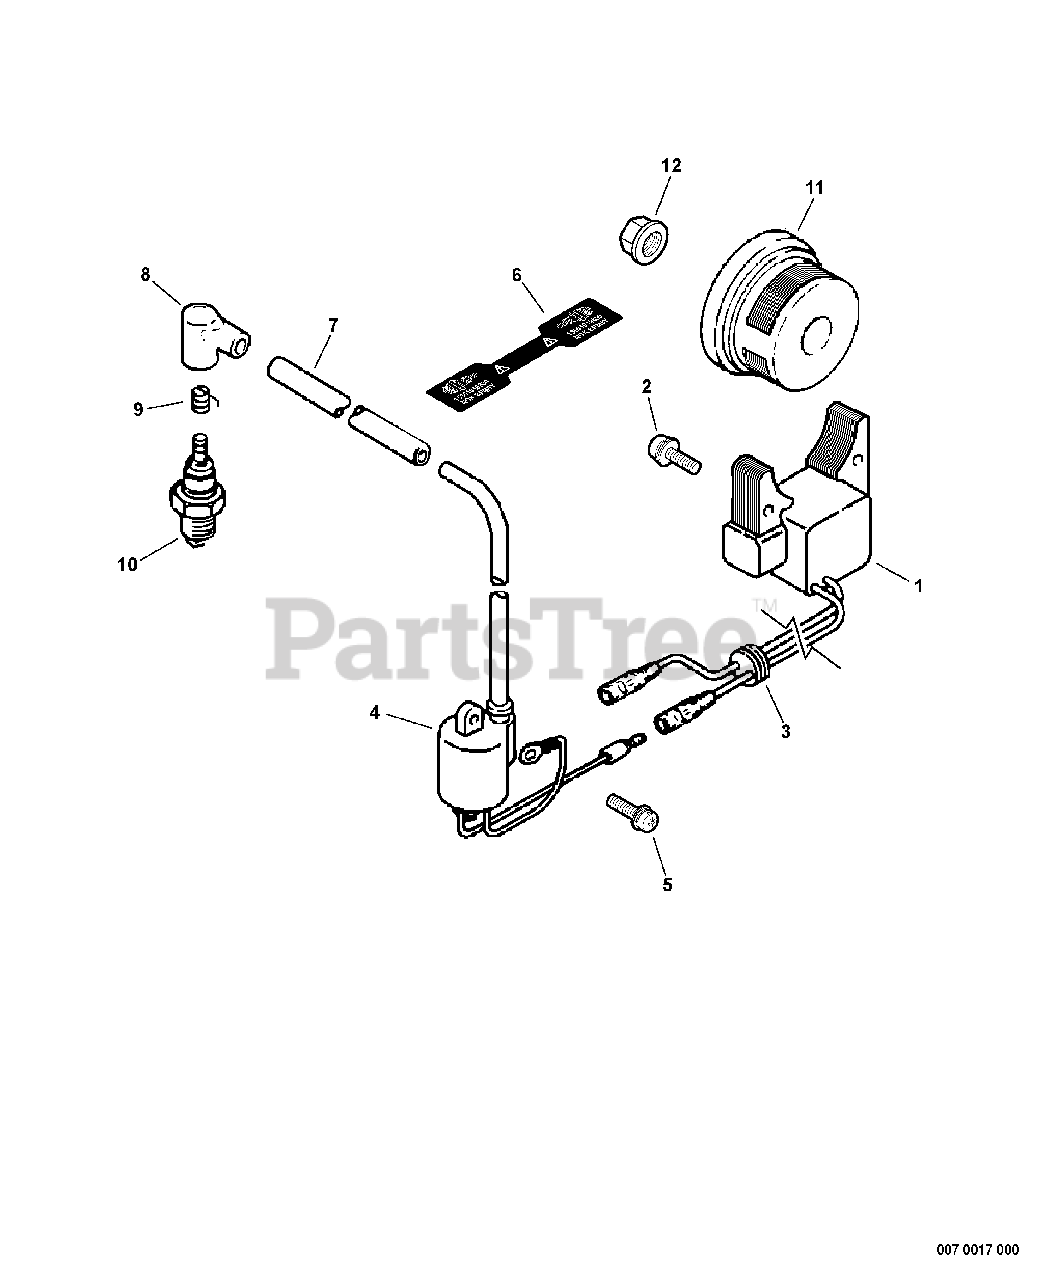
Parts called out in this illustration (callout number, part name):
1	COIL, IGNITION
2	SCREW - 5X25
4	COIL, IGNITION
5	SCREW - 4X16
6	LABEL - SPARK PLUG
8	CAP, SPARK PLUG
9	TERMINAL, SPARK PLUG CAP
10	SPARK PLUG -- BPM-8Y
11	FLYWHEEL
12	NUT - 10 -- FLANGE
